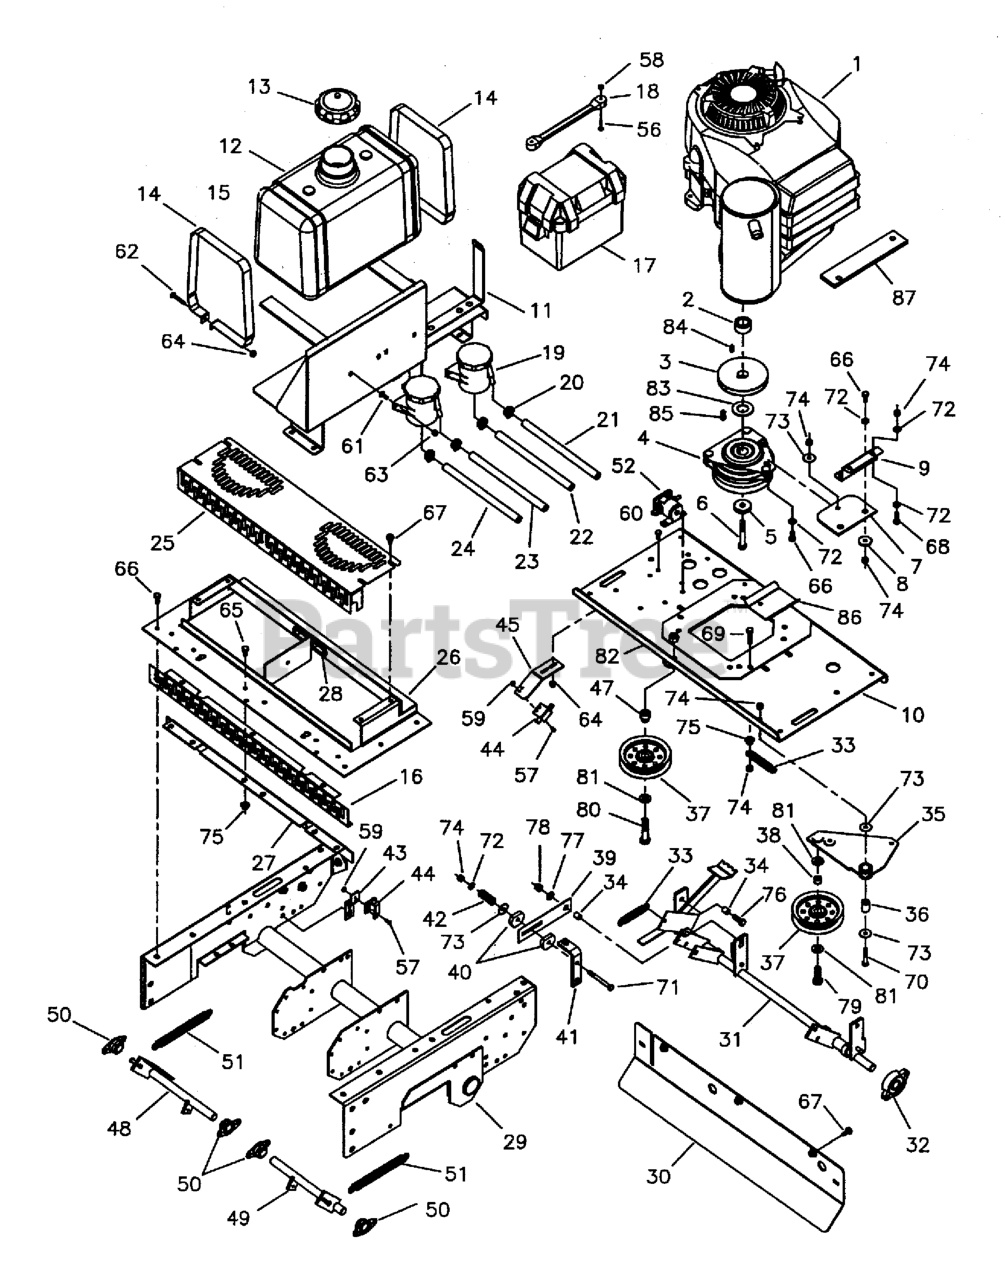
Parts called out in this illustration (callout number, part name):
2	SPACER, 1.13 x 1.75 x 1.50
3	PULLEY, DDSKAV23 Crankshaft
4	CLUTCH, Electric, 1-1/8" Shaft
5	SPACER, .45 x 1.62 x .37
6	CRANKSHAFT BOLT, 7/16 x 2-1/2
7	CLUTCH ANCHOR PAD
8	WASHER, Clutch Anchor
9	ANCHOR, Clutch
10	PLATE, Engine Deck
11	MOUNT, Fuel Tank
12	TANK, FUEL, PLASTIC, 5 GALLON W/ FUEL LINE
13	CAP, GASOLINE, VENTED
14	FUEL TANK STRAP
15	RUBBER PAD
16	ENGINE DECK GUARD
17	BATTERY BOX, W/ DRAIN HOLE
18	RUBBER STRAP
19	RESERVOIR, Hydraulic
20	CLAMP, #6 Hose
21	HOSE, 3/8" PUSH-LOCK, 37.00"
22	HOSE, 3/8 PUSH-LOCK, 26.00
23	HOSE, 3/8" PUSH-LOCK, 43.00"
24	HOSE, 3/8" PUSH-LOCK, 35.00"
25	FAN COVER
26	FAN SHROUD
27	SUPPORT, Engine Deck
28	GROMMET, 1-1/4"
29	ENGINE DECK
30	PLATE, Engine Deck Back
31	SHAFT, Control
32	BEARING, Flange
33	SPRING, Extension
34	SLEEVE
35	ASSM, MOUNT, GROUND DRIVE IDLER - RED
36	SPACER, .32 x .75 x 1.06
37	PULLEY, Backside Idler
38	INSERT, Bearing
39	PLATE, Friction
40	PUCK, Brake
41	SUPPORT, Engine Deck
42	SPRING, Compression
43	MOUNT, Switch
44	SWITCH, PLUNGER, N.O./N.C.
45	MOUNT, Switch
47	INSERT, Bearing Shoulder
48	SHAFT, Brake, Right
49	SHAFT, Brake, Left
50	BEARING, Flange
51	SPRING, Extension
52	SOLENOID, Starter
56	SCREW, #10-24 X 1 RS, CZ
57	SCREW, #10-24 x 1/2
58	NUT, #10-24 Hex Nylon Lock
59	NUT, #10-24 Hex
60	HHCS, 1/4-20 X 0.625, GR5, ZINC/CLEAR
61	BOLT,1/4-20X0.750,GR5,STD NECK,SQ,ZC/CL
62	BOLT, 1/4-20 X 1-1/2
63	NUT, 1/4-20 HEX NYLON LOCK
64	NUT, 1/4-20 HEX SERR. FLANGE
65	BOLT, 5/16-18 x 5/8
66	BOLT, 5/16-18 X 3/4 GD5
67	BOLT, Self-Tapping, 5/16-18 x 3/4
68	BOLT, 5/16-18 X 1 GD5 YZ
69	BOLT, 5/16-18 x 1-1/2 TFL
70	BOLT, 5/16-18 x 1-3/4
71	BOLT, 5/16-18 x 3
72	WASHER, 5/16" SAE
73	WASHER, 5/16" Fender
74	NUT, 5/16-18 Hex Nylon Lock
75	NUT, 5/16-18 HEX SERRATED FLANGE (LARGE)
76	BOLT, 3/8-16 X 1" GD5 CZ
77	WASHER, 3/8 SAE
78	NUT, 3/8-24 Hex Nylon Lock
79	BOLT, 1/2-20 X 1-1/2, GD5 CZ
80	BOLT, 1/2-20 X 2-1/2" GD5 CZ
81	WASHER, 1/2 SAE
82	NUT, Hex, Nylon Lock, 1/2-20
83	SPACER, DDSKAV23 Clutch
84	KEY, 1/4" SQ. X 1-1/4
85	KEY, 1/4 SQ. X 1
86	PAN, Oil Drain
87	SPACER, Engine Block
